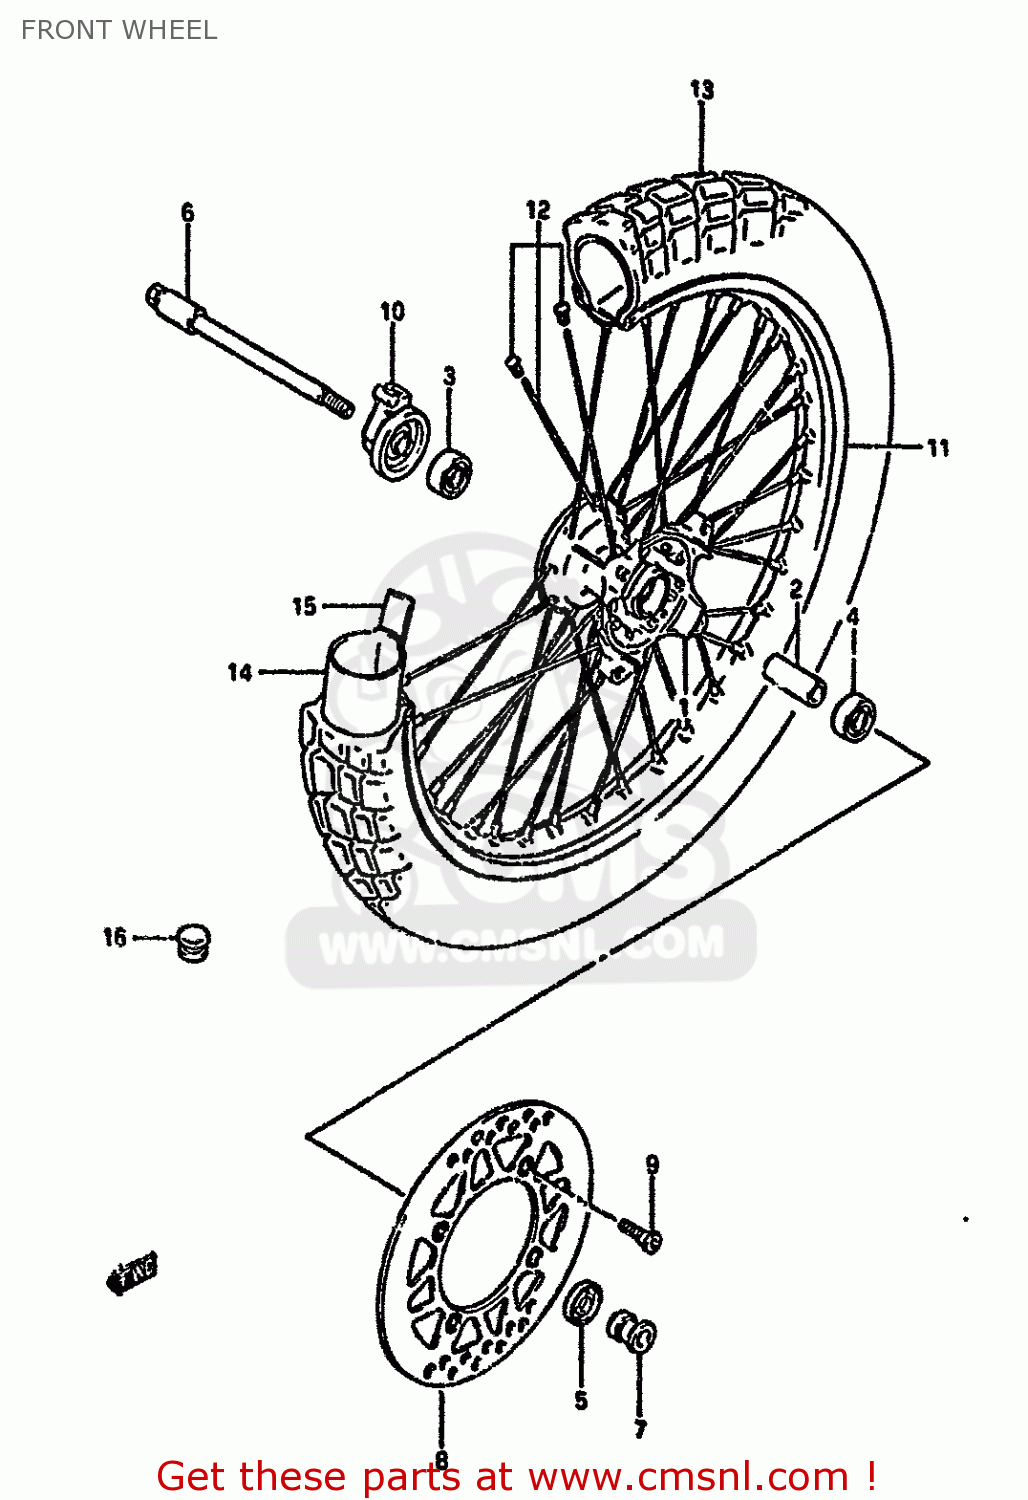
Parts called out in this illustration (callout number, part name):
1	HUB,FR WHEEL
2	SPACER,FR HUB BEARING
3	BEARING
4	BEARING
5	SEAL,HUB LH
6	AXLE,FR
7	SPACER,FR AXLE,L
8	DISC,FR BRAKE
9	BOLT,BRAKE DISC
10	BOX ASSY,SPEEDOMETER GEAR
11	RIM,FR WHEEL(1.60X21)
12	SPOKE SET,FR WHEEL
13	TIRE,FRONT
14	TUBE,INNER
15	PROTECTOR,WHEEL INNER
16	CAP(OD:12)
